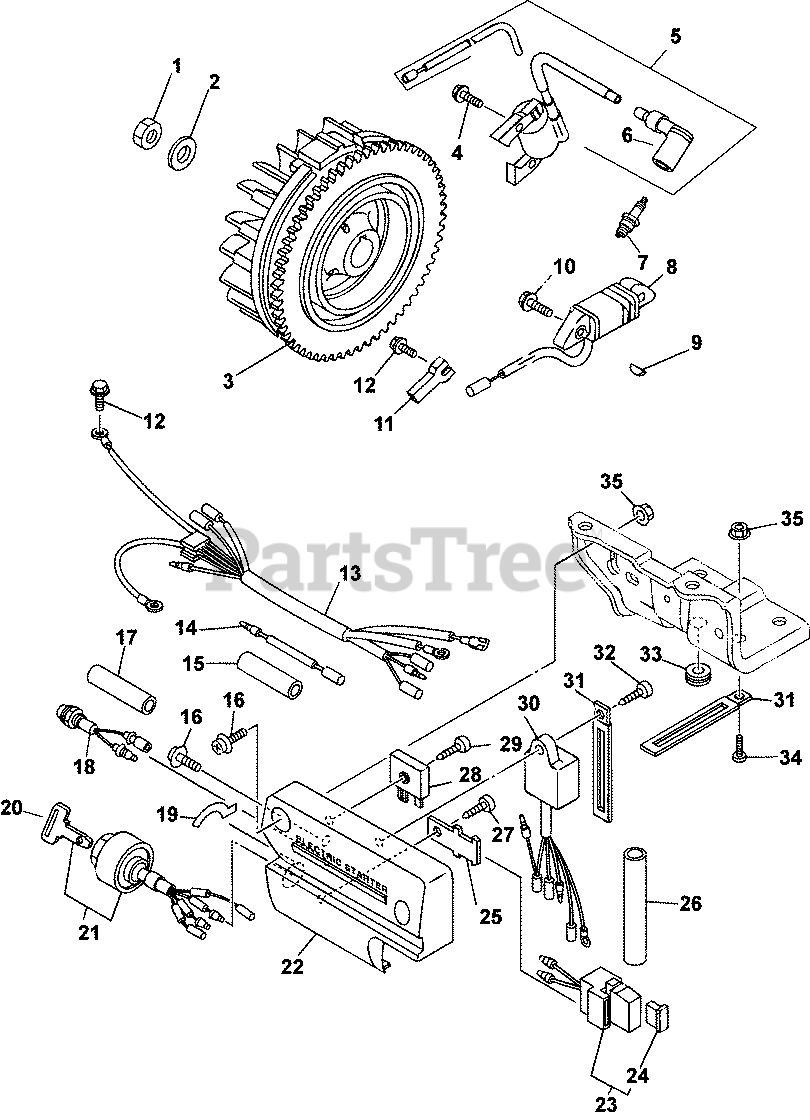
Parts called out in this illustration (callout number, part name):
3	FLYWHEEL, FOR 600 SERIES
5	KIT, IGNIT MODULE (600 SERIES)
6	CAP ASSEMBLY
7	SPARK PLUG
8	STATOR, FOR 600 SERIES SPECS
9	KEY, WOODRUFF
13	LEAD-DISCONTINUED
15	SLEEVE, WIRING
16	SCREW, BIND
17	SLEEVE, WIRE
18	OIL LIGHT
19	DECAL, IGNITION
20	KEY, IGNITION
21	KEYSWITCH, 600 SERIES
22	PANEL, 600 SERIES
23	FUSE HOLDER
26	SLEEVE, WIRE
27	SCREW, TAPPING
28	RECTIFIER / DIODE
30	OIL SWITCH ASSEMBLY -USE 63 099 03-S
34	SCREW, STOP SWITCH
35	NUT, STOP SWITCH
